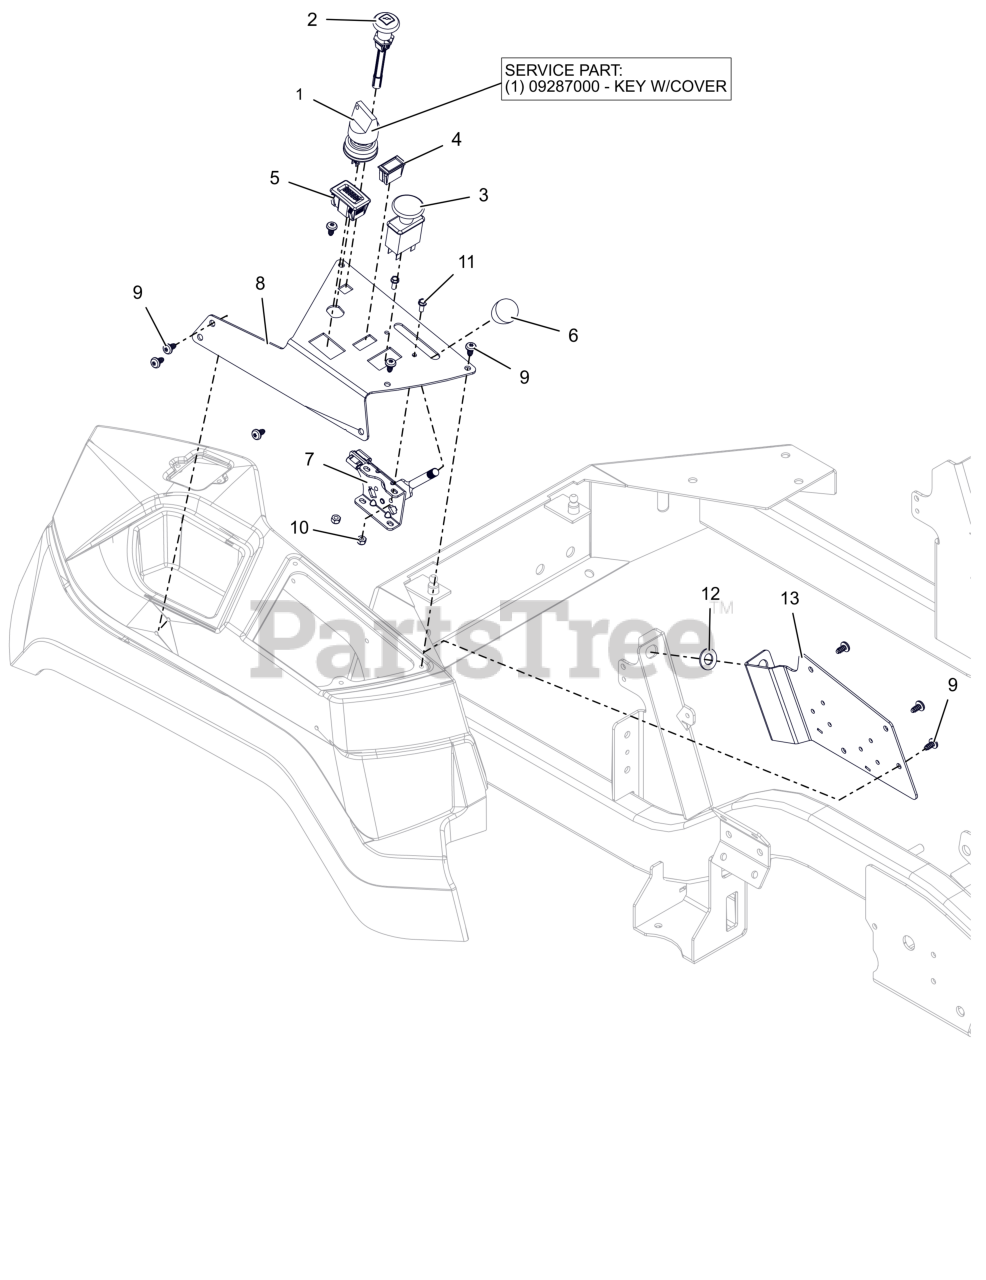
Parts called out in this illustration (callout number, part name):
1	SWITCH, IGNITION
1	KEY, W/ SHIELD
2	CABLE - CHOKE, SNAP-IN
3	SWITCH, CLUTCH
4	SWITCH,BLANK
5	METER, HOUR
6	KNOB-CONTROL-BLACK .38-16X.50
7	CABLE, PRO THROTTLE CONTROL
8	PLATE, APEX CONTROL PANEL
9	SCR-PAN .25-15X.50 6L H/LZB500
10	NUT-LK-NYL #10-24 G2 ZCC
11	BLT, HWH #10-24X.50 ZCC
12	WSHR-FL-NYL .518X1.000X.080
13	BRKT, FENDER/RELAY MOUNTING
